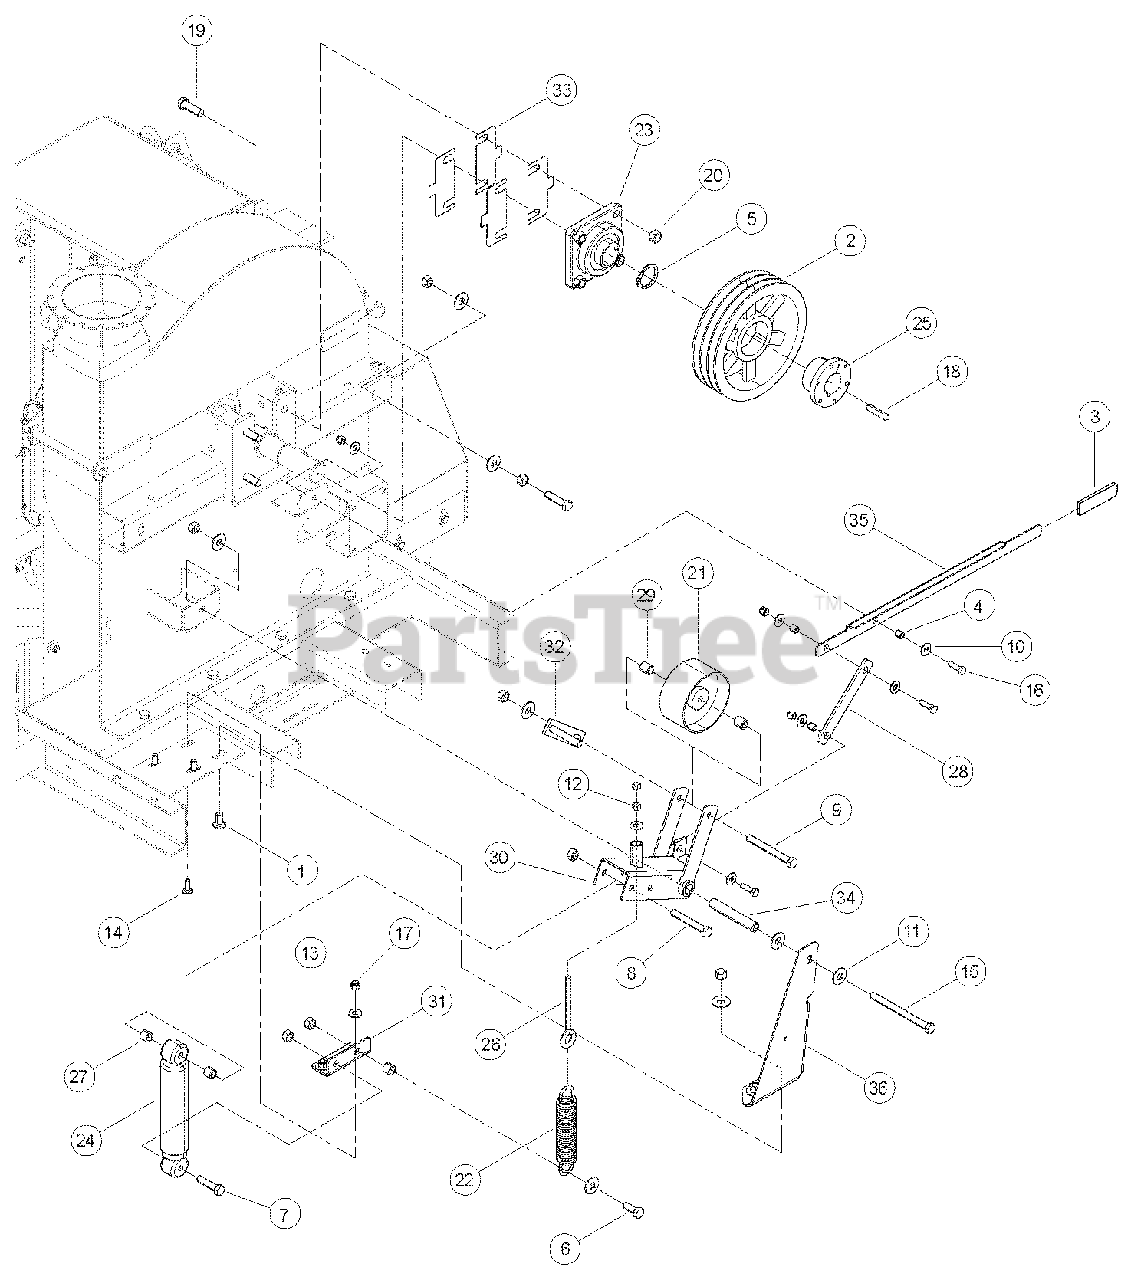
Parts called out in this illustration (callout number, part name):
1	BOLT, 1/2 X 1 CRG
2	SHEAVE, 3B 9.4 DISK
3	GRIP, CLUTCH HANDLE
4	BUSHING, 3/8 X 1/2 SLEEVE LUBE
5	SNAP RING, 1-3/4 EXT. HEAVY DUTY
6	BOLT, 1/2 X 1-1/4 HEX HD
7	BOLT, 1/2 X 2 HEX HD GR5 ZP
8	BOLT, 1/2 X 3-1/2 HEX HD GR5 ZP
9	BOLT, 1/2 X 4-1/2 HEX HD GR5 ZP
10	WASHER, 3/8 FLAT ZP
11	WASHER, 1/2 FLAT ZP
12	NUT, 3/8 HEX
13	NUT, 1/2 CENTERLOCK GRB ZP
14	BOLT, 3/8 X 1 CRG
15	BOLT, 1/2 X 6 HEX HD
16	BOLT, 3/8 X 1-1/4 HEX HD
17	NUT, 3/8 NE NYLOCK ZP
18	KEY, 3/8 X 2 SQUARE
19	BOLT, 9/16 X 1-3/4
20	NUT, 9/16 CENTERLOCK GRB ZP
21	PULLEY, 5 X 2.5 IN. IDLER
22	SPRING, 7-3/4 EXTENSION
23	BEARING, 1-3/4 4 BOLT FLANGE
24	ABSORBER, IDLER SHOCK
25	BUSHING, 1-3/4 SK
26	I-BOLT, 3/8 X 5
27	SPACER, .75 X .62
28	LINK, CLUTCH ENGAGEMENT
29	SPACER, IDLER SHAFT
30	WELDMENT, IDLER ARM
31	BRACKET, SPRING ANCHOR
32	WELDMENT, BELT PIN
33	SHIM, 20 GA.
34	BUSHING, IDLER PIVOT
35	LEVER, CLUTCH ENGAGEMENT
36	BRACE, IDLER
